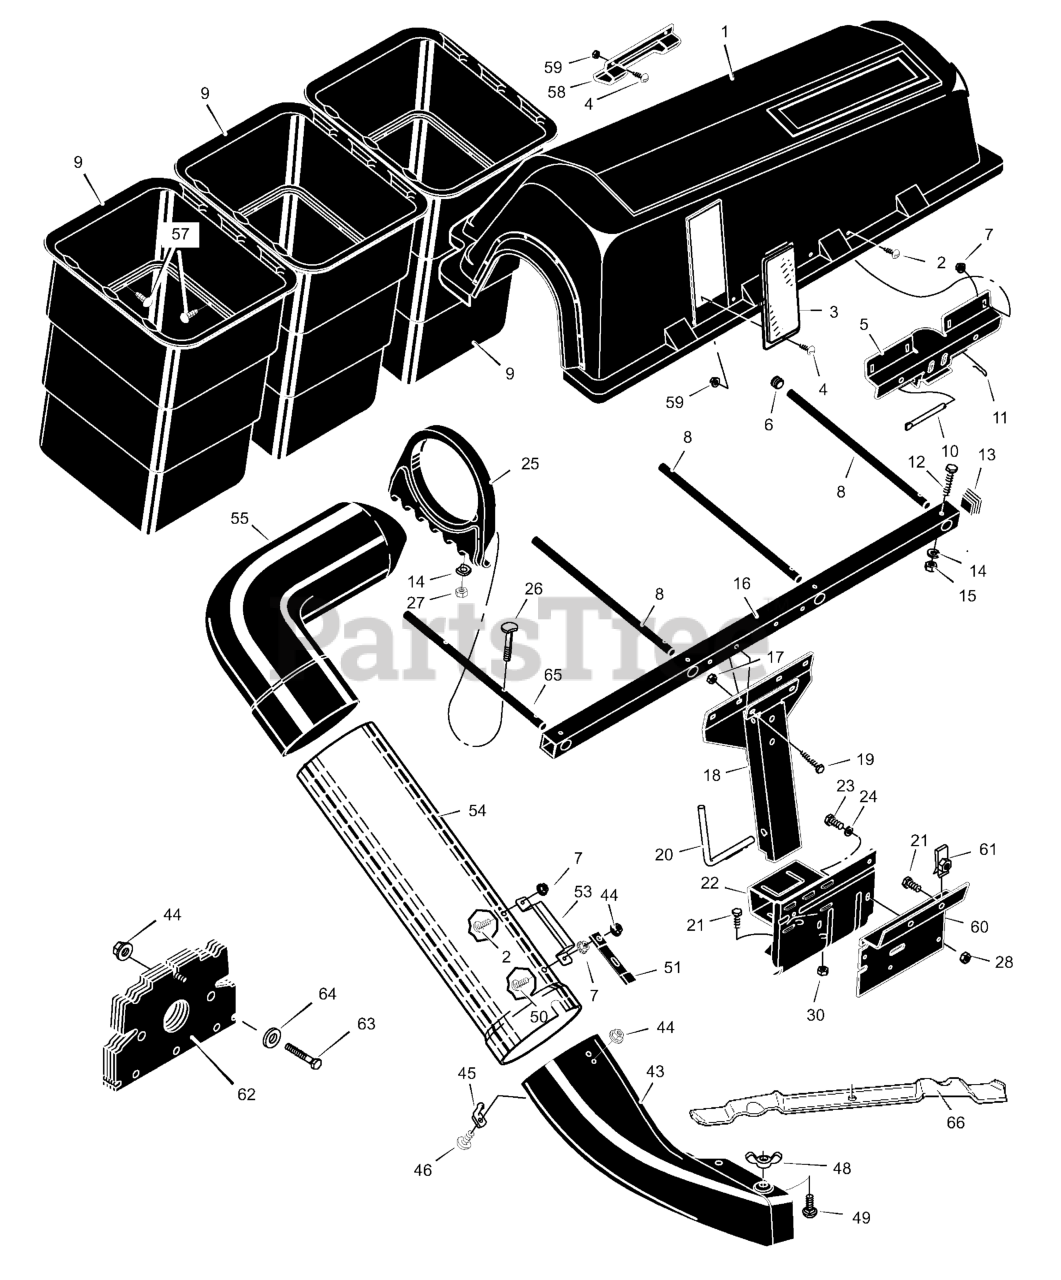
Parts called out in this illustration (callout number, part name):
1	Cover, Bagger
5	Hinge, Bracket
7	Nut, Hex
8	Tube, Container
9	Container
10	Pin, Cover Hinge
11	Pin, Hair
13	Plug
14	Lockwasher
16	Tube, Support
17	Nut
18	Assembly, Channel
20	Pin, Channel Mount
21	Bolt, Hex
22	Assembly, Bagger Mount
23	Bolt, Hex
25	Holder, Elbow
27	Washer
28	Nut, Super Flange
30	Nut, Hex
43	Tube, Extension
44	Locknut, Flange
45	Pin, Latch
46	Bolt, Carriage
48	Wingnut
49	Bolt, Carriage
51	Latch, Rubber
53	HANDLE, Connect Tube
54	Tube, Connecting
57	Fastener, Panel
58	Handle, Plastic
59	Nut, Hex
60	Bracket, Adapter
62	Weight, Front
65	Tube, Right Container
66	Blade, High Lift
